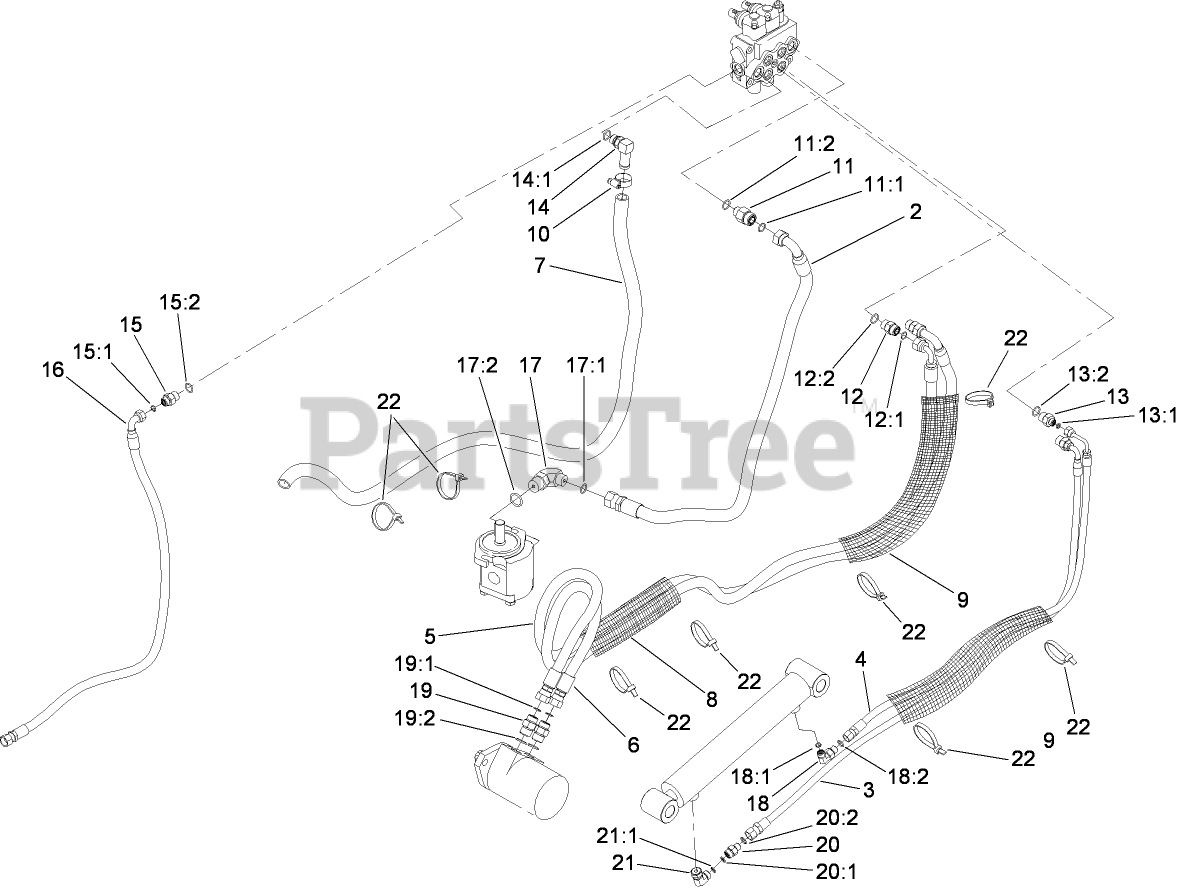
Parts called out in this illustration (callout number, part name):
2	HOSE-HYD
3	HOSE-HYD
4	HOSE-HYD
5	HOSE-HYD
6	HOSE-HYD
7	HOSE-RETURN
8	SLEEVE-PROTECTIVE
9	SLEEVE-PROTECTIVE
10	CLAMP-HOSE
11	FITTING-STR
11:1	O-RING
11:2	O-RING
12	FITTING-STRAIGHT
12:1	O-RING
12:2	O-RING
13	FITTING-STR
13:1	O-RING
13:2	O-RING
14	FITTING-ELB 90
14:1	O-RING
15	FITTING-STRAIGHT
15:1	O-RING
15:2	O-RING
16	HYD HOSE ASM
17	FITTING-ELBOW 90
17:1	O-RING
17:2	O-RING
18	FITTING-ELBOW 90
18:1	O-RING
18:2	O-RING
19	FITTING-STRAIGHT
19:1	O-RING
19:2	O-RING
20	FITTING-STRAIGHT
20:1	O-RING
20:2	O-RING
21	FITTING-HYD, 90 DEG
21:1	O-RING
22	TIE-CABLE
